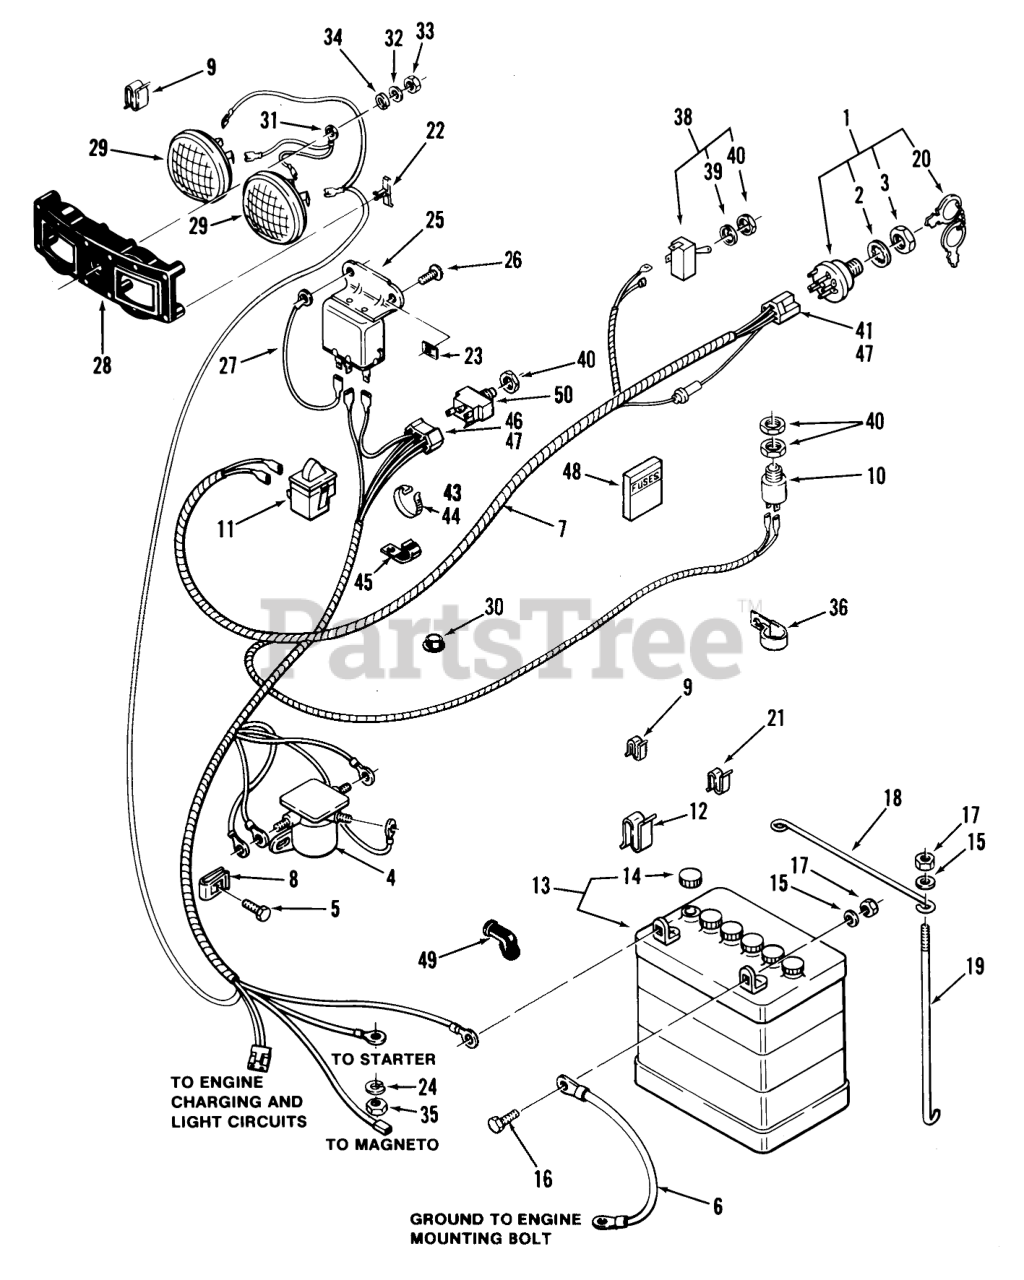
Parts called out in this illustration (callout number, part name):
1	SWITCH-IGNITION
2	LOCKWASHER
4	SOLENOID
5	HEX WASHER HD SCREW
6	Wire
7	Wiring Harness Assy-B-165 Only
7	Wiring Harness Assy-B-115 Only
8	Speed Nut
9	SPEED CLIP
10	SWITCH
11	SWITCH INTERLOCK
12	Clip
13	Battery
16	Bolt
17	Nut
18	ROD-HOLD DOWN
19	Hook
20	Key-EL
21	SPEED CLIP
22	CLIP-SPRING
23	Speed Nut
24	Washer
25	Relay
26	Screw 10-24 X 5/8
27	RELAY-GROUND WIRE
28	Headlight Retainer
29	HEADLAMP
30	BUSHING-NYLON .75
31	LIGHT GROUND WIRE
32	WASHER 5/16 SAE
33	Nut
34	Washer-Lock
35	Nut
36	CLAMP
38	SWITCH-LIGHTS
39	TAB-WASHER
40	NUT-HEX
41	CONNECTOR-5 WAY-SERV
42	TERMINAL-TAB RCPT
43	EDGE TRIM 4IN OF 102896
44	Cable Tie
45	CLIP
46	CONNECTOR 5 WAY
47	Terminal
49	Terminal Cover
50	SWITCH-CLUTCH
